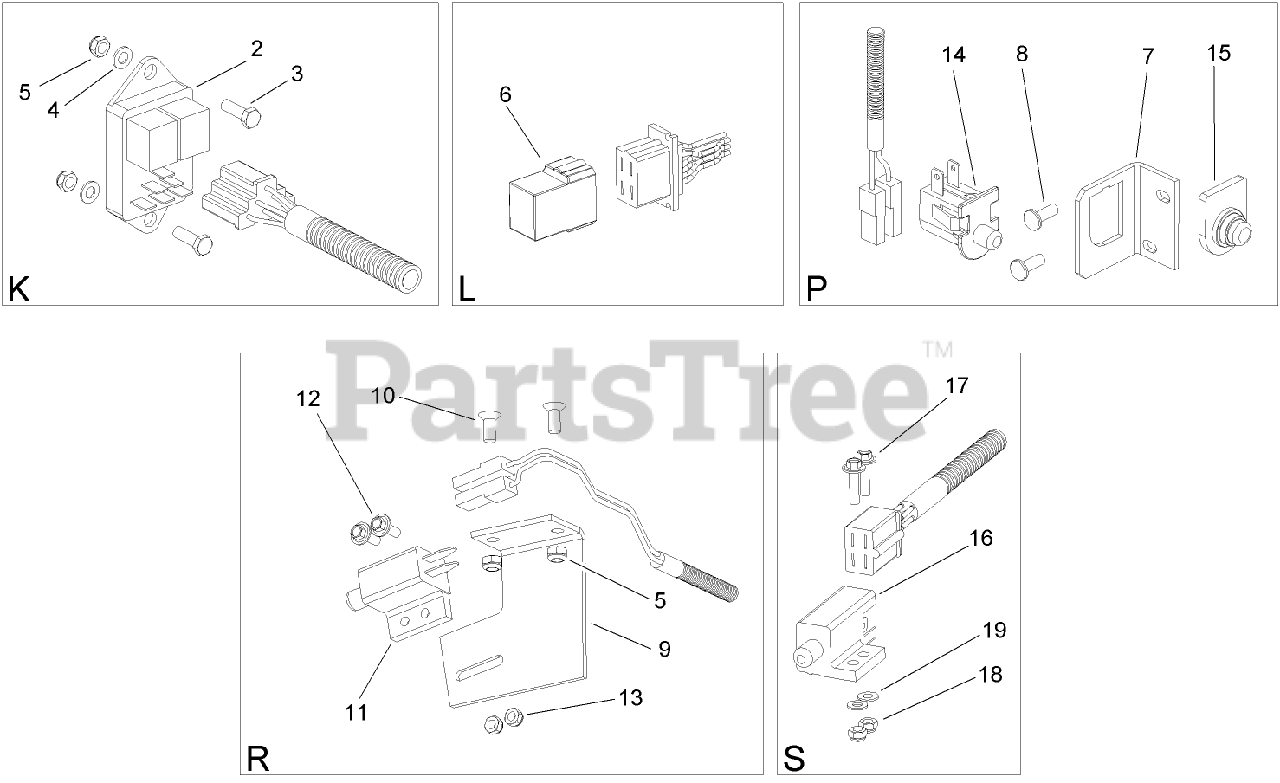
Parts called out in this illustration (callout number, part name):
2	MODULE-CLUTCH
3	SCREW-HH
4	WASHER
5	NUT-LOCK
6	CIRCUIT-MEMORY
7	Holder-Switch
9	HOLDER-SWITCH
11	SWITCH-POLE, SINGLE
13	NUT-HEX
14	SWITCH-DELTA
15	Cover-Switch
16	Switch-Delta
18	NUT-LOCK
19	WASHER
